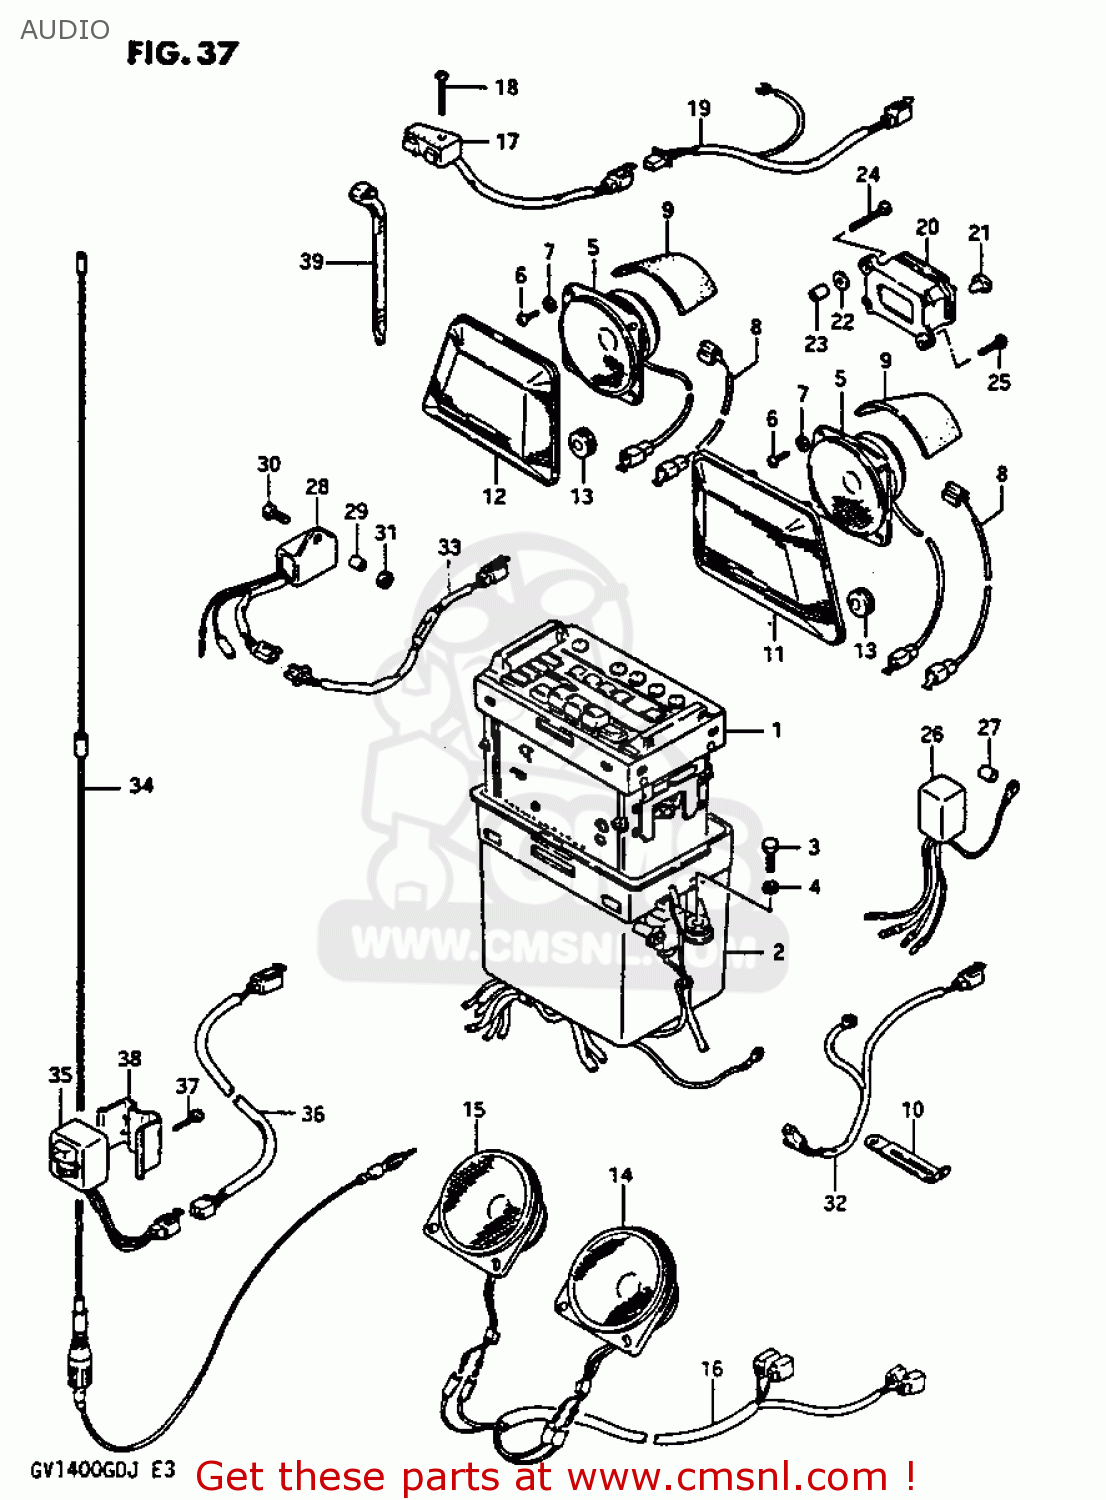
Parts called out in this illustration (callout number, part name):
1	TUNER ASSEMBLY
2	CASE
3	BOLT,M6X1X20
4	WASHER,LOCK
5	SPEAKER
6	SCREW
7	WASHER
8	WIRE,SPEAKER LEAD
9	COVER,SPEAKER
10	CLAMP
11	GRILLE,SPEAKER,RIGHT
12	GRILE,SPEAKER,L
13	CUSHION
14	SPEAKER
15	SPEAKER ASSEMBLY,REAR,LEFT
16	WIRE,SPEAKER LEAD
17	SWITCH,RADIO CHANNEL SELECT
18	SCREW
19	WIRE,RADIO CHANNEL SELECTOR
20	INDICATOR ASSEMBLY,TUNER C
21	BULB 14V
22	WASHER (4X16X1.2)
23	SPACER
24	SCREW
25	SCREW
26	CONDENSER ASSEMBLY,REGULATOR
27	SPACER (6.5X10.5X13.5)
28	FILTER ASSEMBLY,FAN MOTOR
29	SPACER (6.8X10X10)
30	SCREW
32	WIRE,AUDIO POWER SOURCE
33	WIRE,FAN MOTOR LEAD
34	ANTENNA ASSEMBLY,TUNER
35	CONTROLLER ASSEMBLY,TUNER
36	WIRE,CHANNEL SELECT SWITCH
37	SCREW
38	SWITCH
39	CLAMP(L:125)
